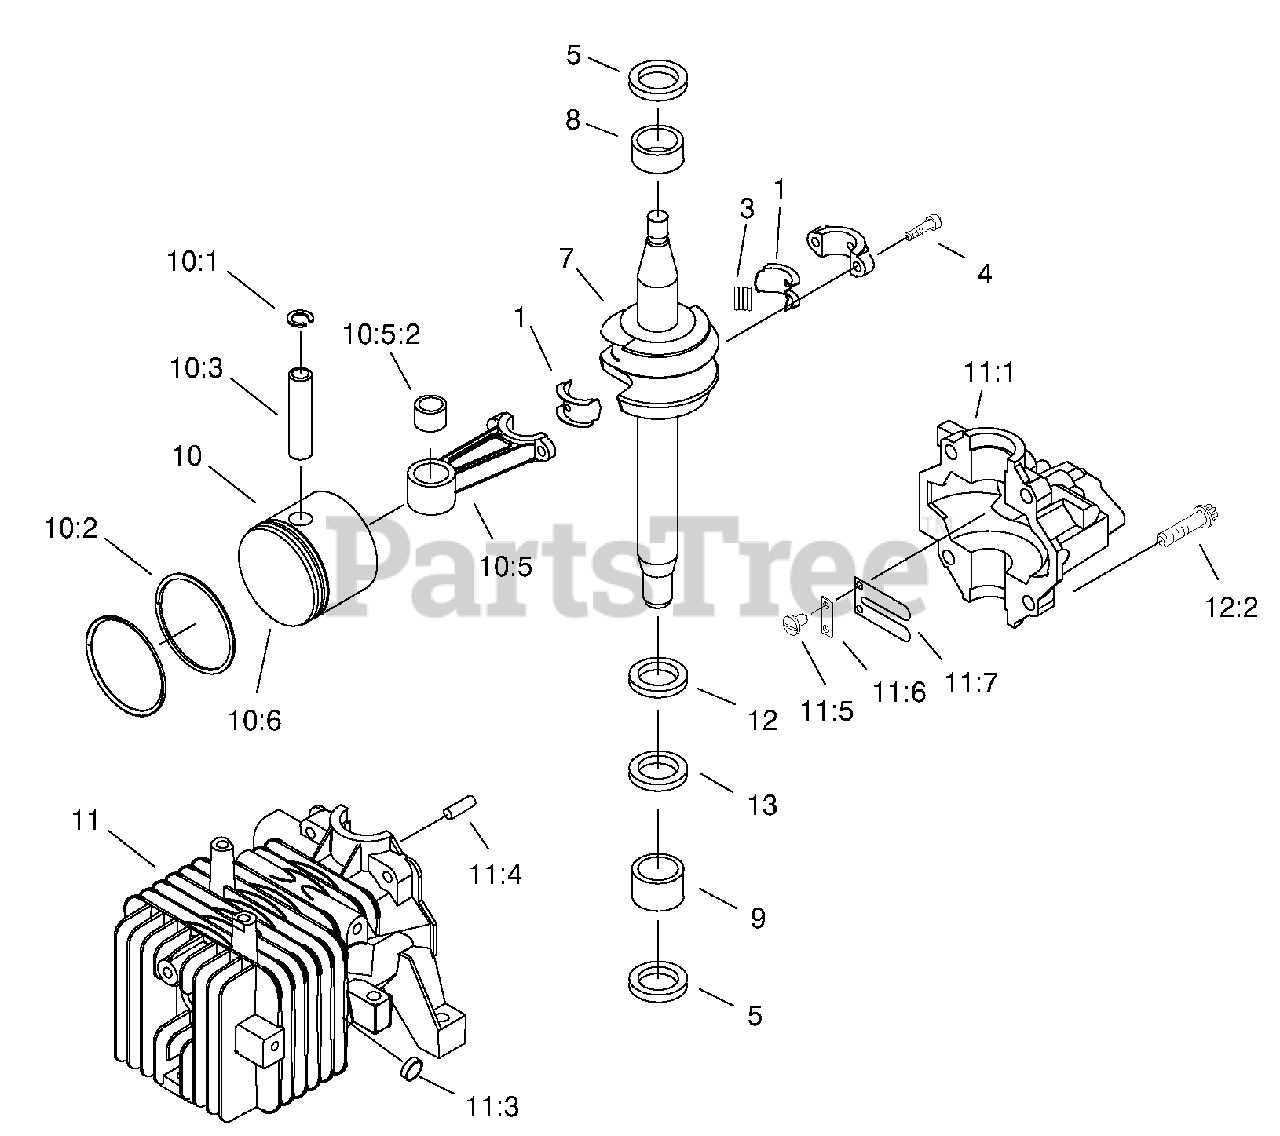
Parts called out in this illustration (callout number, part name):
1	Liner ASM
3	Bearing-Needle
4	Screw-HSH
5	Seal-Oil
7	Crankshaft
8	Bearing
9	Bearing
10	Piston & Connecting Rod
10:1	Ring-Retaining
10:2	F-Ring Set
10:3	Pin-Wrist
10:5	Connecting Rod ASM
10:6	Piston & Ring
11	Cylinder & Crankcase ASM
11:1	Cyl & C/Case
11:2	Screw-HWH
11:3	Plug-Core
11:5	Screw-HH
11:6	Plate-Backup, Reed
11:7	Reed-Carburetor
12	Bearing-Thrust
13	Washer-Thrust
